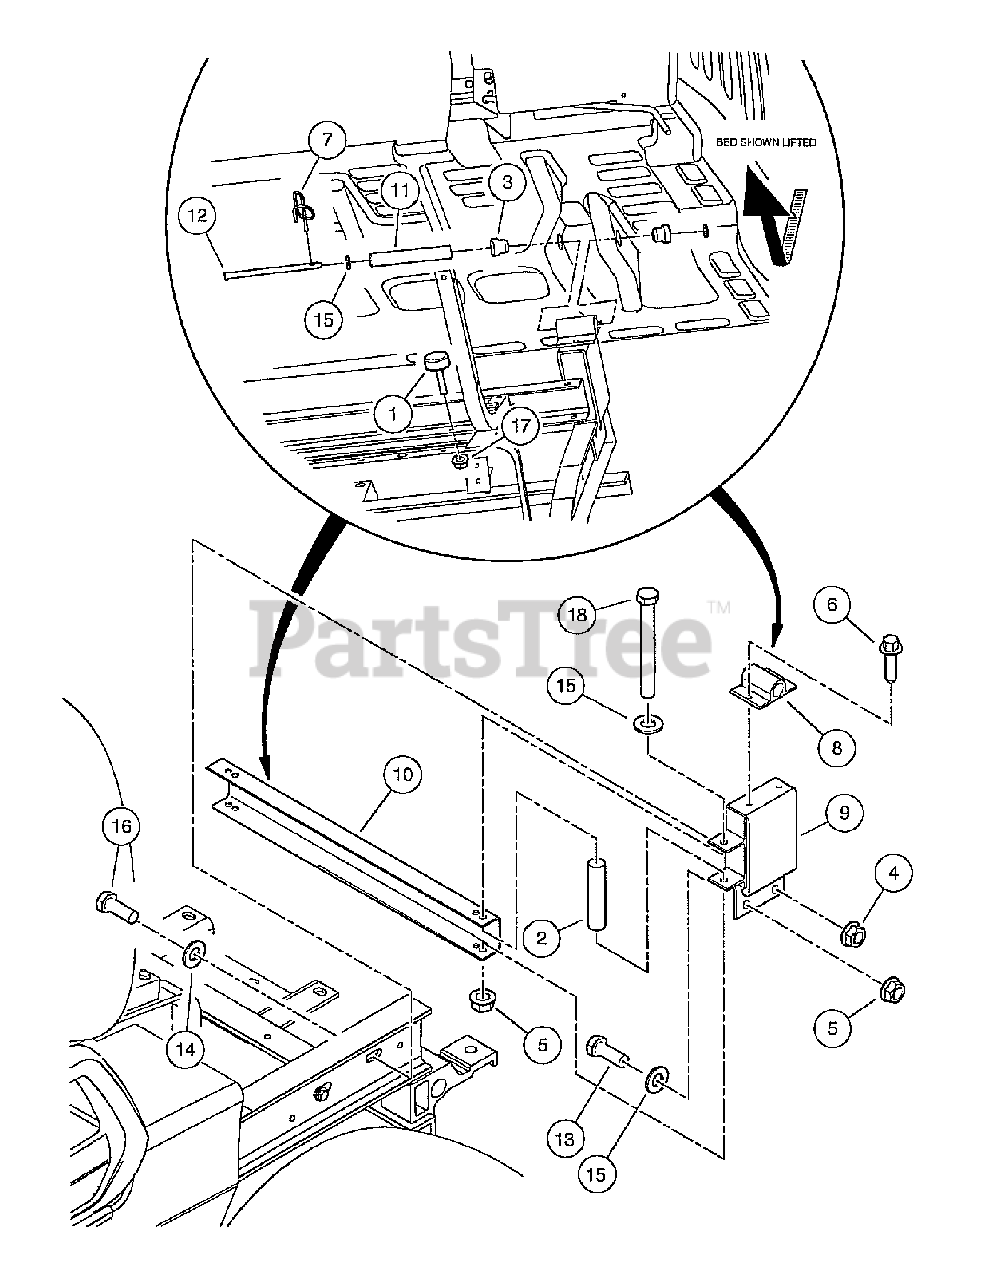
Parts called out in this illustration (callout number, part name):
1	Bumper, Brake Pedal Rubber
2	Bushing, Steel
3	Bushing, Urethane
4	Locknut, 1/4-20 Hex Whiz
5	Locknut, 3/8-16 Flanged Dimple
6	Screw, M8X1.25X30, Hex
7	Rue Ring - 1/2"
8	Hinge, Roto Bed
9	Support, Hinge
10	Stiffener, Bed Support
11	Bushing, Steel
12	Pin, Clevis, 3/8
13	Screw, 3/8-16 X 1.00 Hx Hd Cap
14	Washer, 1/4 Type A Narrow Flat
15	Washer, 3/8 Type A Flat
16	Screw, 1/4-20 X 0.75 Hex-Head Cap
17	Locknut, 1/4-20 Nylon Insert
18	Screw, 3/8-16 X 3.375 Hex Cap
